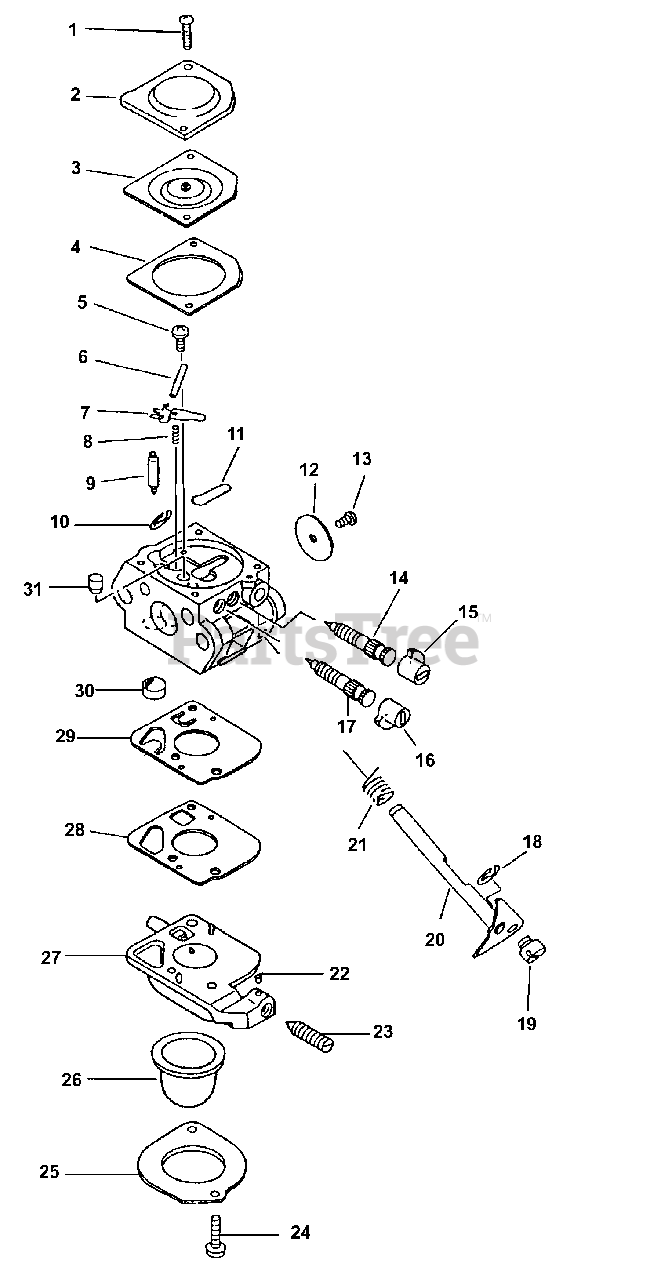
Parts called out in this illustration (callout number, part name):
2	COVER, METERING
3	DIAPHRAGM, METERING
4	GASKET, METERING
5	SCREW, METERING LEVER PIN
6	PIN, METERING LEVER
7	LEVER, METERING
8	SPRING, LEVER METERING
9	NEEDLE, INLET
10	RING, RETAINING
11	PLUG, WELCH
12	VALVE, THROTTLE
14	NEEDLE - LOW SPEED
15	CAP, LIMITER
16	CAP, LIMITER
17	NEEDLE - HIGH SPEED
18	RING, RETAINING
20	SHAFT, THROTTLE
21	SPRING, RETURN
22	PIECE, FRICTION
23	SCREW, IDLE ADJUST
24	SCREW, RETAINER
25	RETAINER, PURGE BULB
26	BULB, PURGE
27	BASE, PURGE
28	GASKET, PURGE
29	DIAPHRAGM, PURGE
30	STRAINER
31	NOZZLE, CHECK VALVE
A	REPAIR KIT
B	DIAPHRAGM/GASKET KIT
